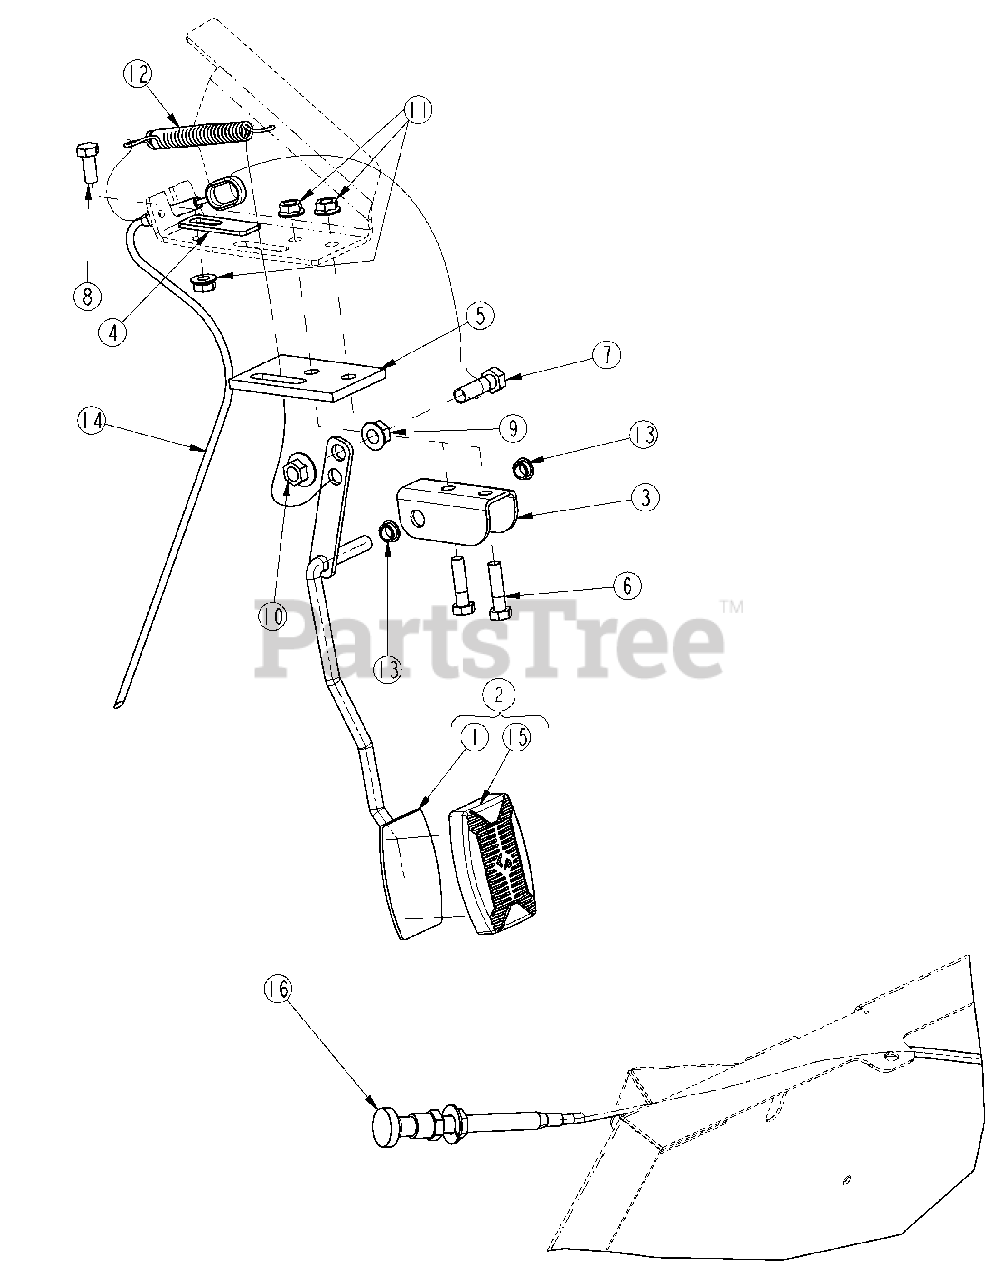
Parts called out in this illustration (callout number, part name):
1	GAS PEDAL WELDMENT
2	GAS PEDAL W/PAD ASSEMBLY
3	GAS PEDAL MOUNT
4	GAS PEDAL ADJUSTMENT PLATE
5	BODY MOUNT SPACER .375 THICK Use as needed
6	HHCS 5/16-18X1 1/4 GR5
7	BOLT, HEX 3/8-16 X 1 1/4 GR5
8	BOLT, HEX 5/16-18 X 3/4 GR5 YELLOW DIE
9	NUT, SERRATED FLANGE 3/8-16 PLT
10	NUT MAC-LOK FLG 3/8-16 GR F
11	SPRING EXT .5OD .075W 2.75LG
12	NUT HEX LOCK 5/16-18 FLG.
13	BUSHING NYLON 3/8ID (SNAP IN)
14	THROTTLE CABLE
15	BRAKE/ACCELERATOR PEDAL RUBBER
16	CHOKE CABLE 84.0"
